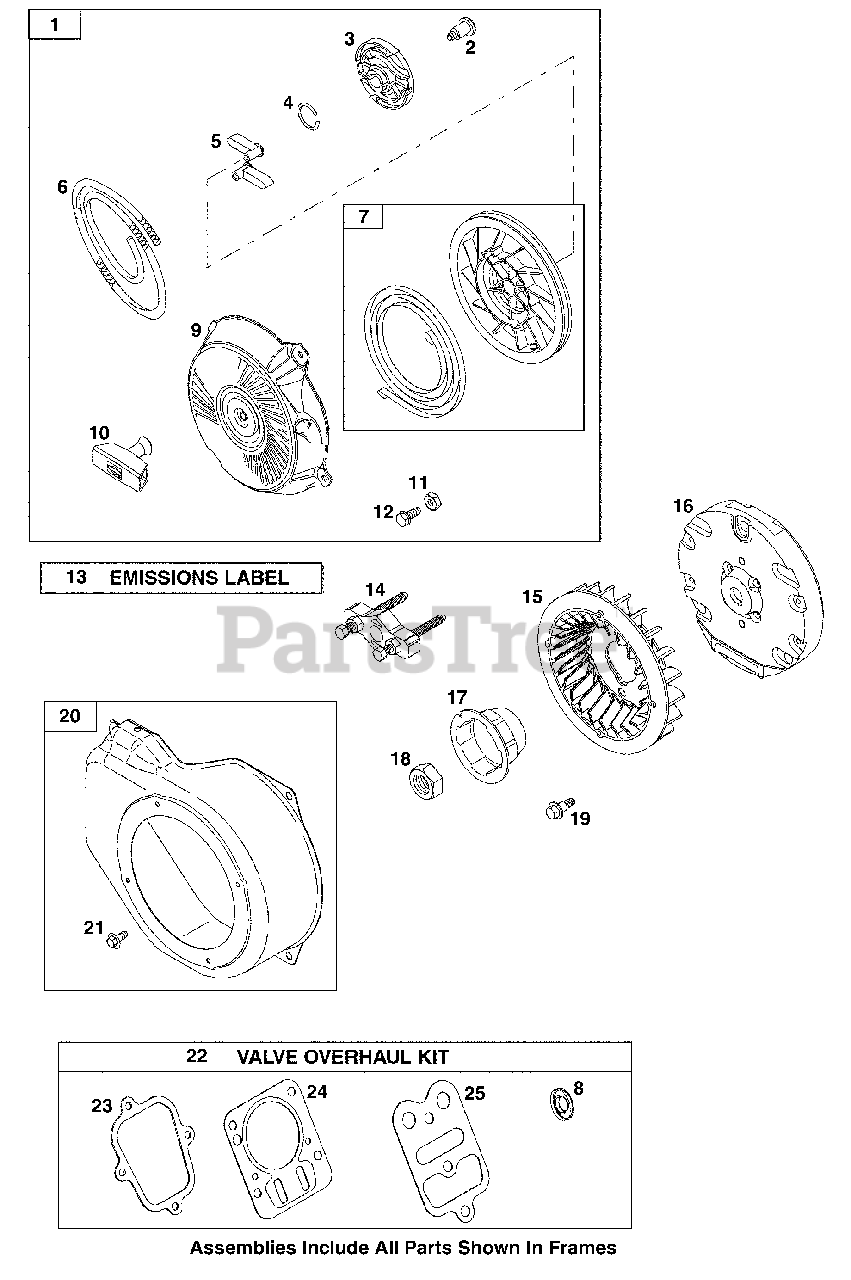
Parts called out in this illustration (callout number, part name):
1	Starter-Rewind
2	Screw
3	Plate-Pawl Friction
4	Spring-Friction
5	Pawl-Ratchet
6	Rope-Starter
7	Pulley/Spring Assembly
8	Seal-Valve
9	Rewind Starter Housing
10	Starter Rope Grip
11	Nut
12	Screw
13	Emissions Label
14	Flywheel Puller
15	Fan-Flywheel
17	Cup-Flywheel
18	Nut
19	Screw
20	Housing-Blower
21	Screw
22	Kit-Valve Overhaul
23	Gasket-Rocker Cover
24	Cylinder Head Gasket
25	Cylinder Head Plate Gasket
